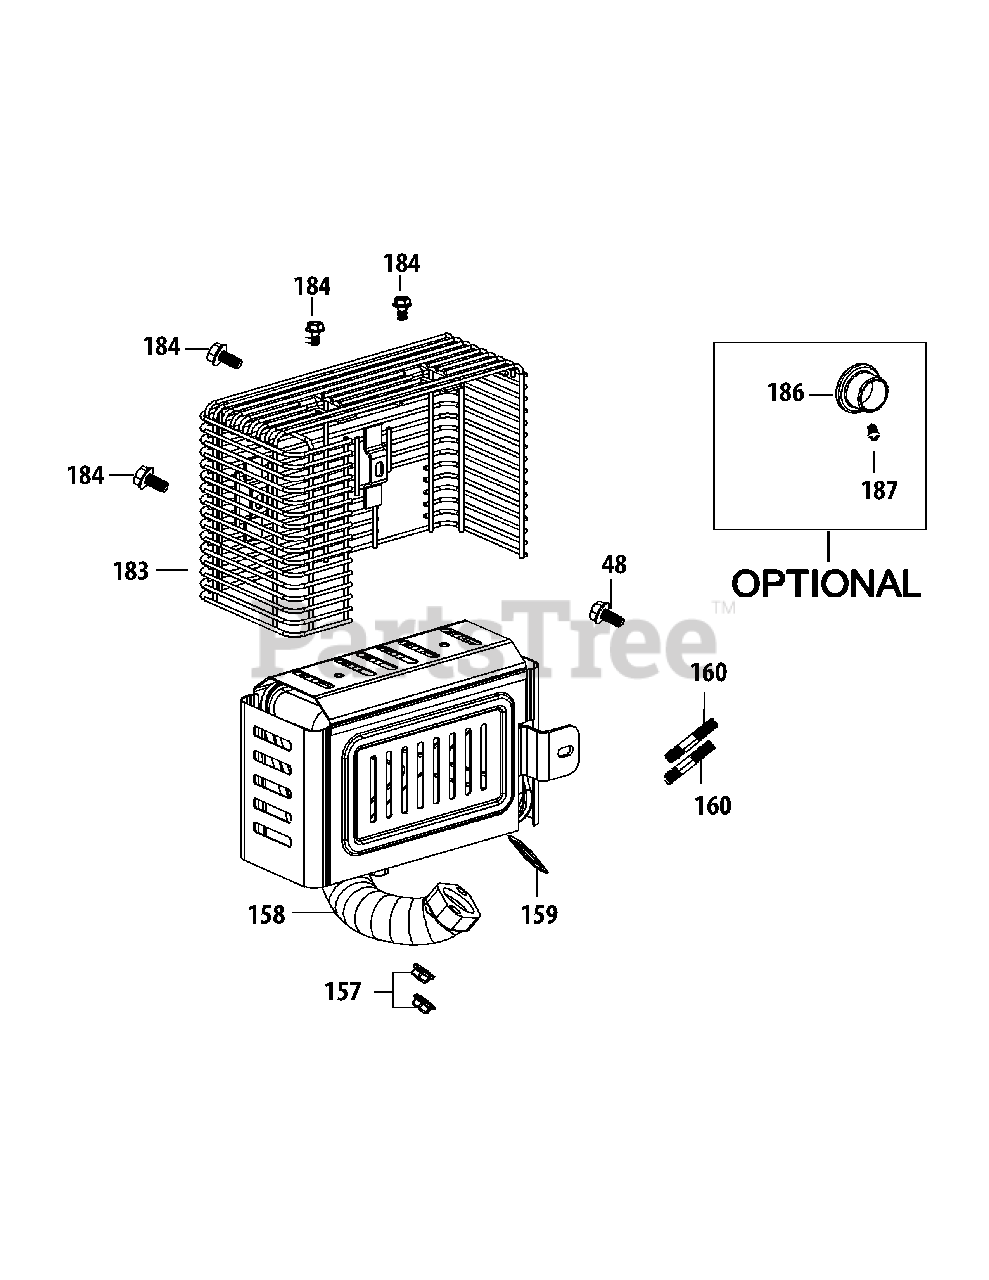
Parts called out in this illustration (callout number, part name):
48	Bolt M6x14
158	Muffler Assembly
159	Exhaust Pipe Gasket
160	Muff Stud M8x47
160	Muffler Stud Assembly
183	Wire Mesh Shield
184	Bolt M6x12
186	Spark Arrestor
187	Spark Arrestor Screw
